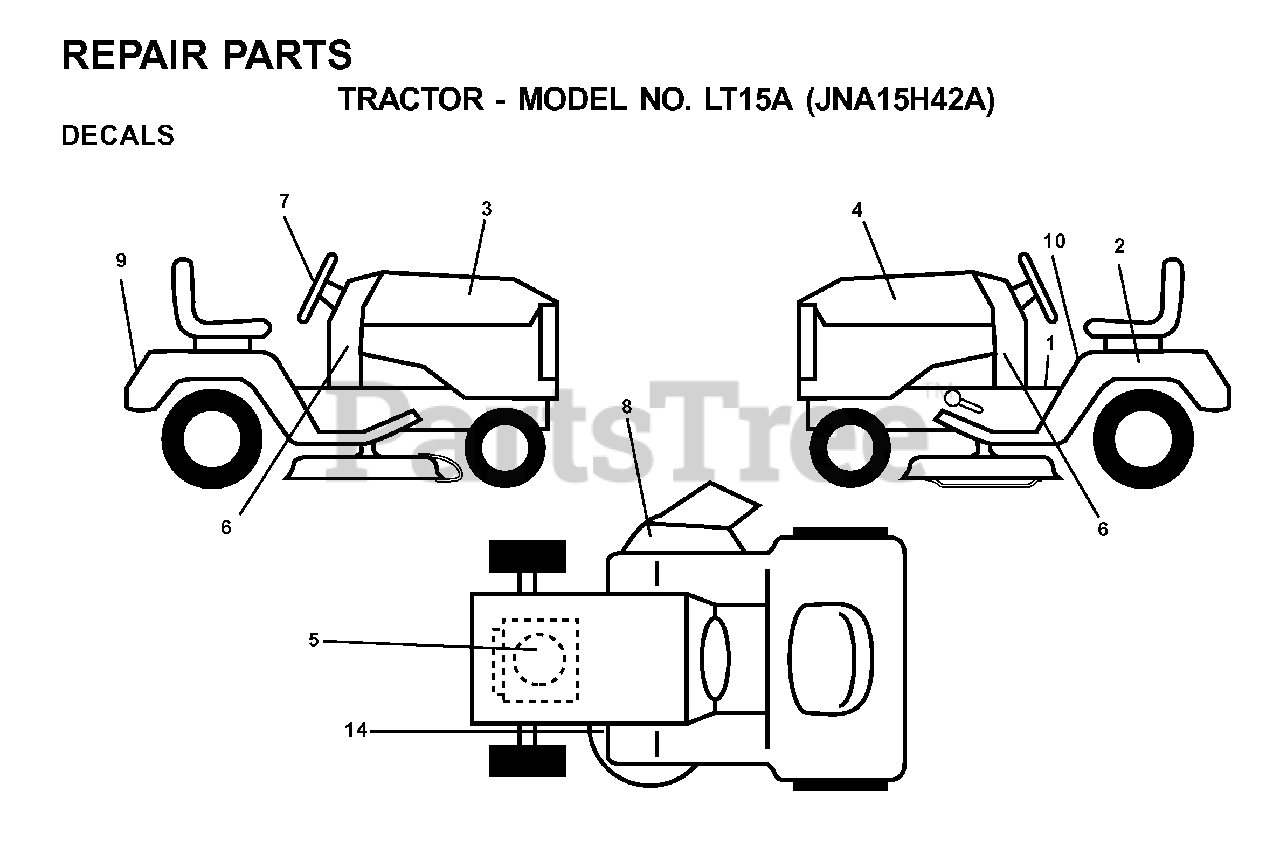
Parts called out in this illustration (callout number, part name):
1	DECAL SET
2	DECAL BTRY SYMBOLS
8	DECAL.WARN.KEEP.HAND.AWAY
10	DECAL FENDER DANGER
14	DECAL V BELT SCHEMATIC
